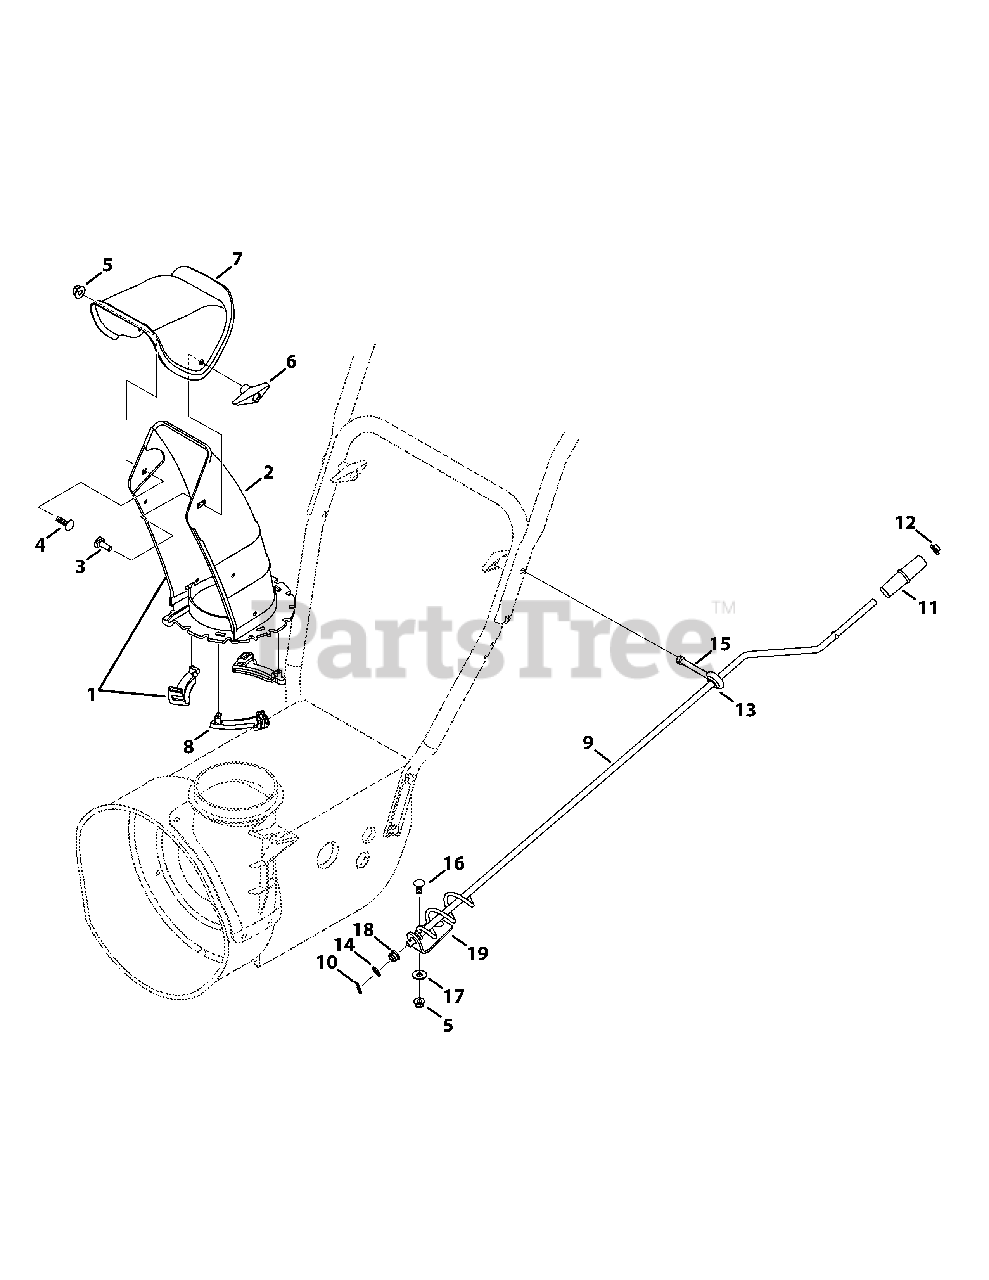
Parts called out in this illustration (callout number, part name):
1	Lower Chute Assembly
2	Lower Chute
3	Carriage Bolt, 5/16-18 x 1.00
4	Carriage Bolt, 5/16-18 x .750
5	Flange Lock Nut, 5/16-18
6	Wing Knob
7	Upper Chute
8	Flange Keeper
10	Cotter Pin, .072 x 1.13
11	Crank Knob
12	Push Cap, 3/8
13	Rubber Grommet
14	Flat Washer, .375 x .738 x .063
16	Carriage Screw, 5/16-18 x 1.00
17	Flat Washer, .349 x .879 x .063
18	Plastic Bushing, .380 ID
19	Chute Crank Bracket
